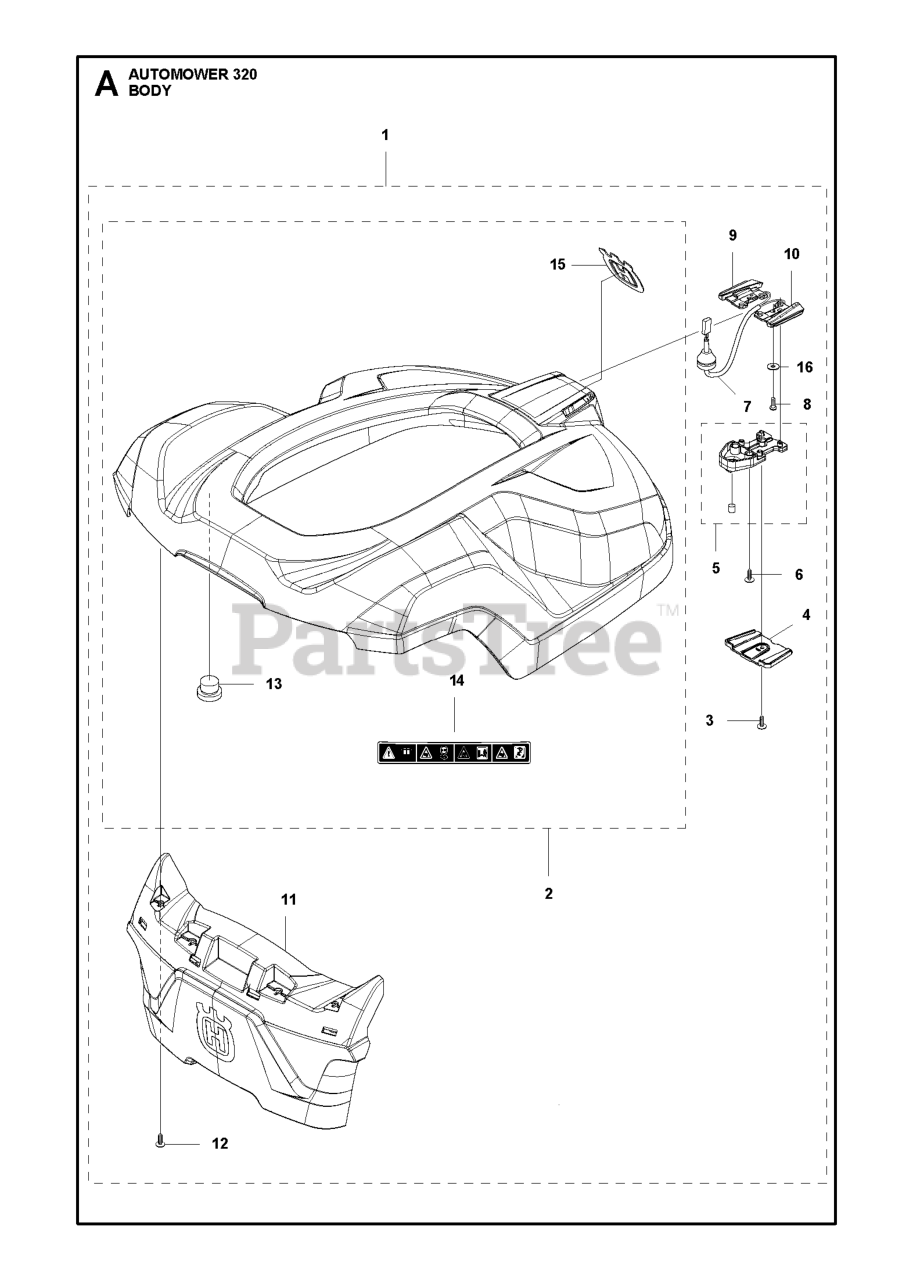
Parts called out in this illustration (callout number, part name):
3	SCREW 14MM
6	SCREW 14MM
11	BUMPER REAR
12	SCREW ITXPANT
13	CAP SNAPLOC
14	LABEL WARNING P15
15	DECAL HUSQVARNA CROWN HEIGHT 5
